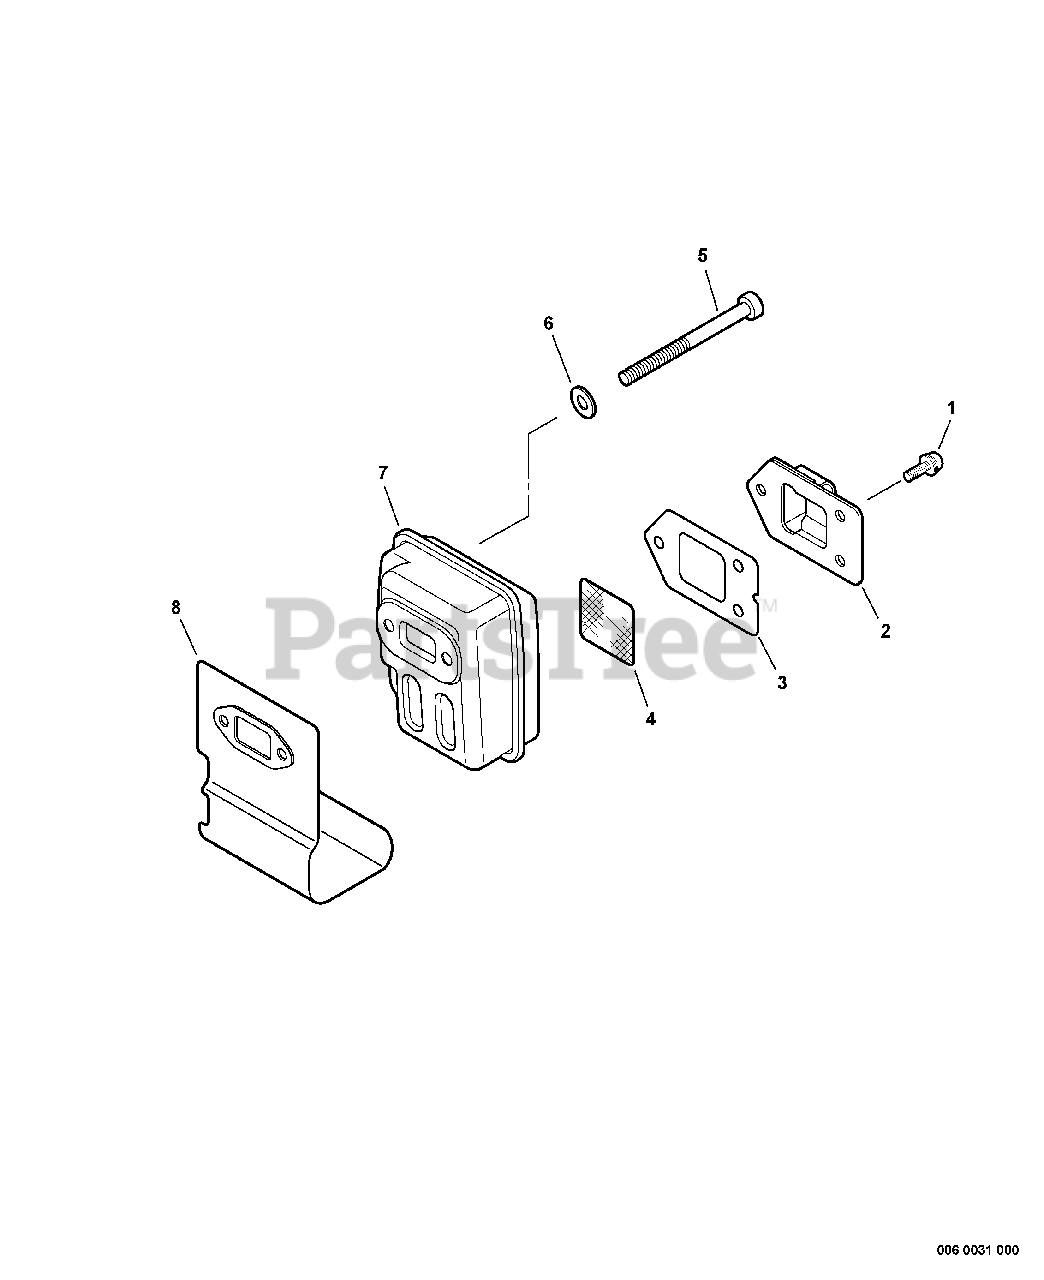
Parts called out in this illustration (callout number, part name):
1	SCREW 4×10
2	GUIDE, EXHAUST
3	GASKET, EXHAUST
4	SCREEN, SPARK ARRESTER
5	BOLT M5×50
6	WASHER, FLAT 5.5×10×0.8
8	SHIELD, EXHAUST
